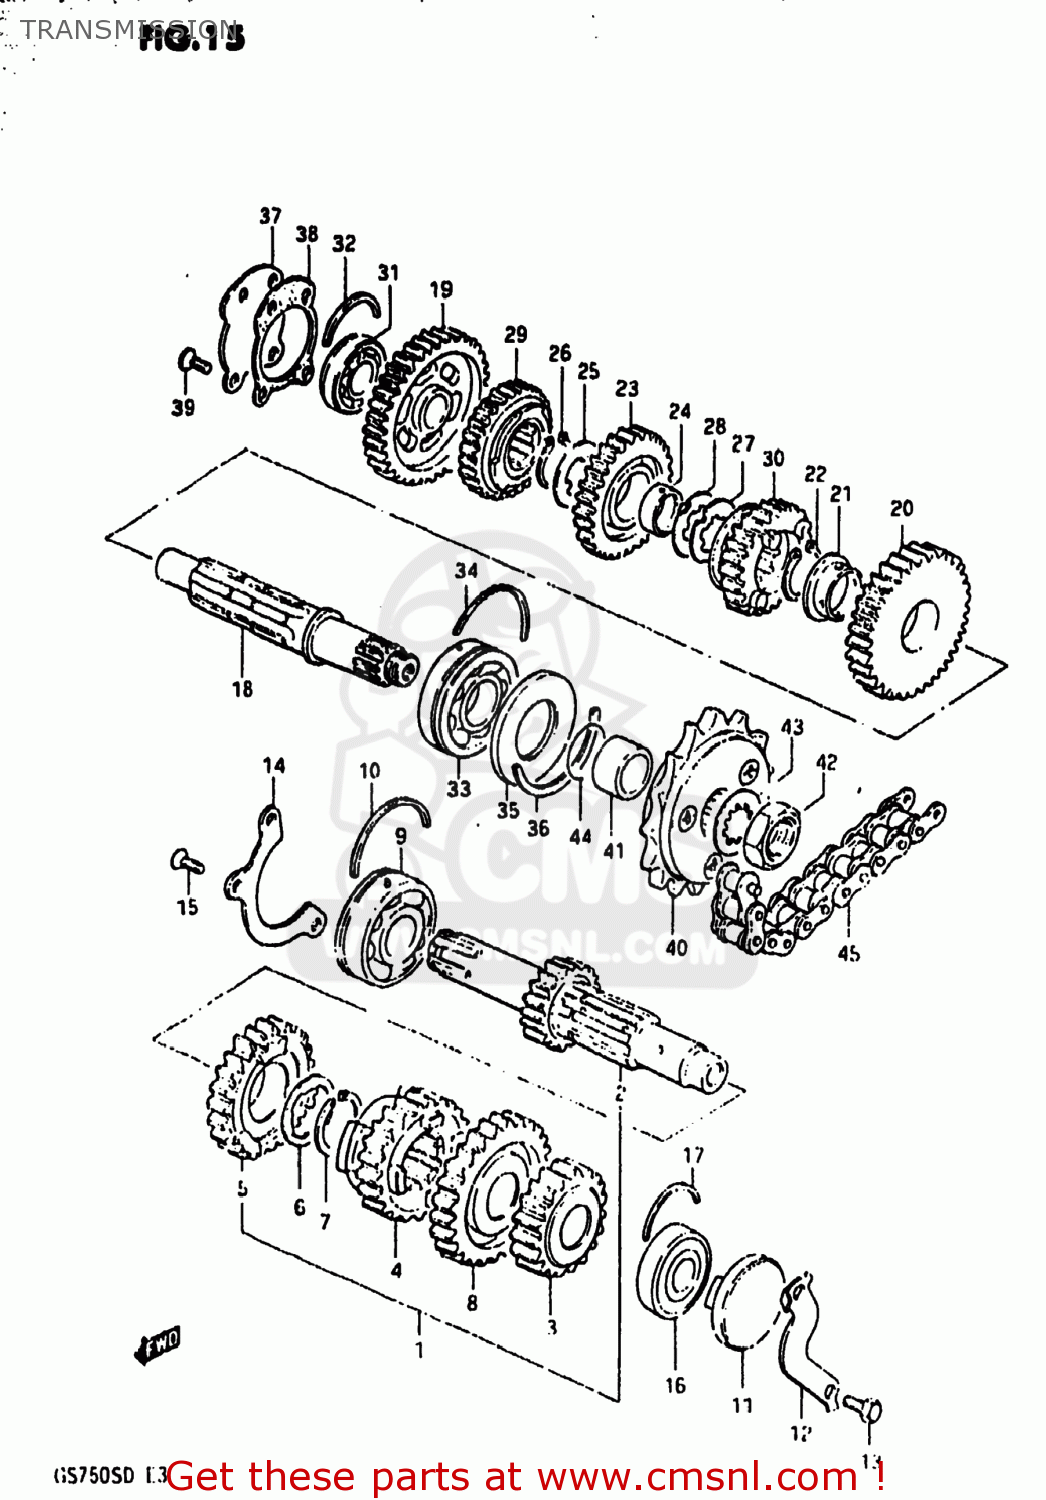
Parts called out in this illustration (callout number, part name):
1	SHAFT ASSEMBLY,COUNTER
2	SHAFT,COUNTER
3	GEAR,SECOND DRIVE
4	GEAR,THIRD DRIVE
5	GEAR,FOURTH DRIVE
6	WASHER,LOCK
7	CIRCLIP
8	GEAR,FIFTH DRIVE
9	BEARING(25X62X17)
10	C-RING
11	PLUG
12	RETAINER,CL PUSH ROD OIL SEAL
13	BOLT
14	RETAINER,CNTR SHAFT BEARING
15	SCREW
16	BEARING(20X47X14)
17	C RING
18	SHAFT,DRIVE
19	GEAR,FIRST DRIVEN
20	GEAR,SECOND DRIVEN
21	BUSH(28X32X2)
22	CIRCLIP
23	GEAR,THIRD DRIVEN
24	BUSH,3RD DRIVEN GEAR
25	WASHER,LOCK
26	CIRCLIP
27	WASHER,LOCK
28	WASHER
29	GEAR,FOURTH DRIVEN
30	GEAR,FIFTH DRIVEN
31	BEARING
32	C RING
33	BEARING(25X62X17)
34	C-RING
35	SEAL,OIL(32X62X7)
36	C RING
37	PLATE,DRIVE SHAFT
38	GASKET,DRIVESHAFT PLATE (MCA)
39	SCREW
40	SPROCKET,ENGINE
41	SPACER(25X32X18.6)
42	NUT
43	WASHER
44	O RING(D:1,ID:24.5)
45	CHAIN ASSEMBLY,DRIVE
